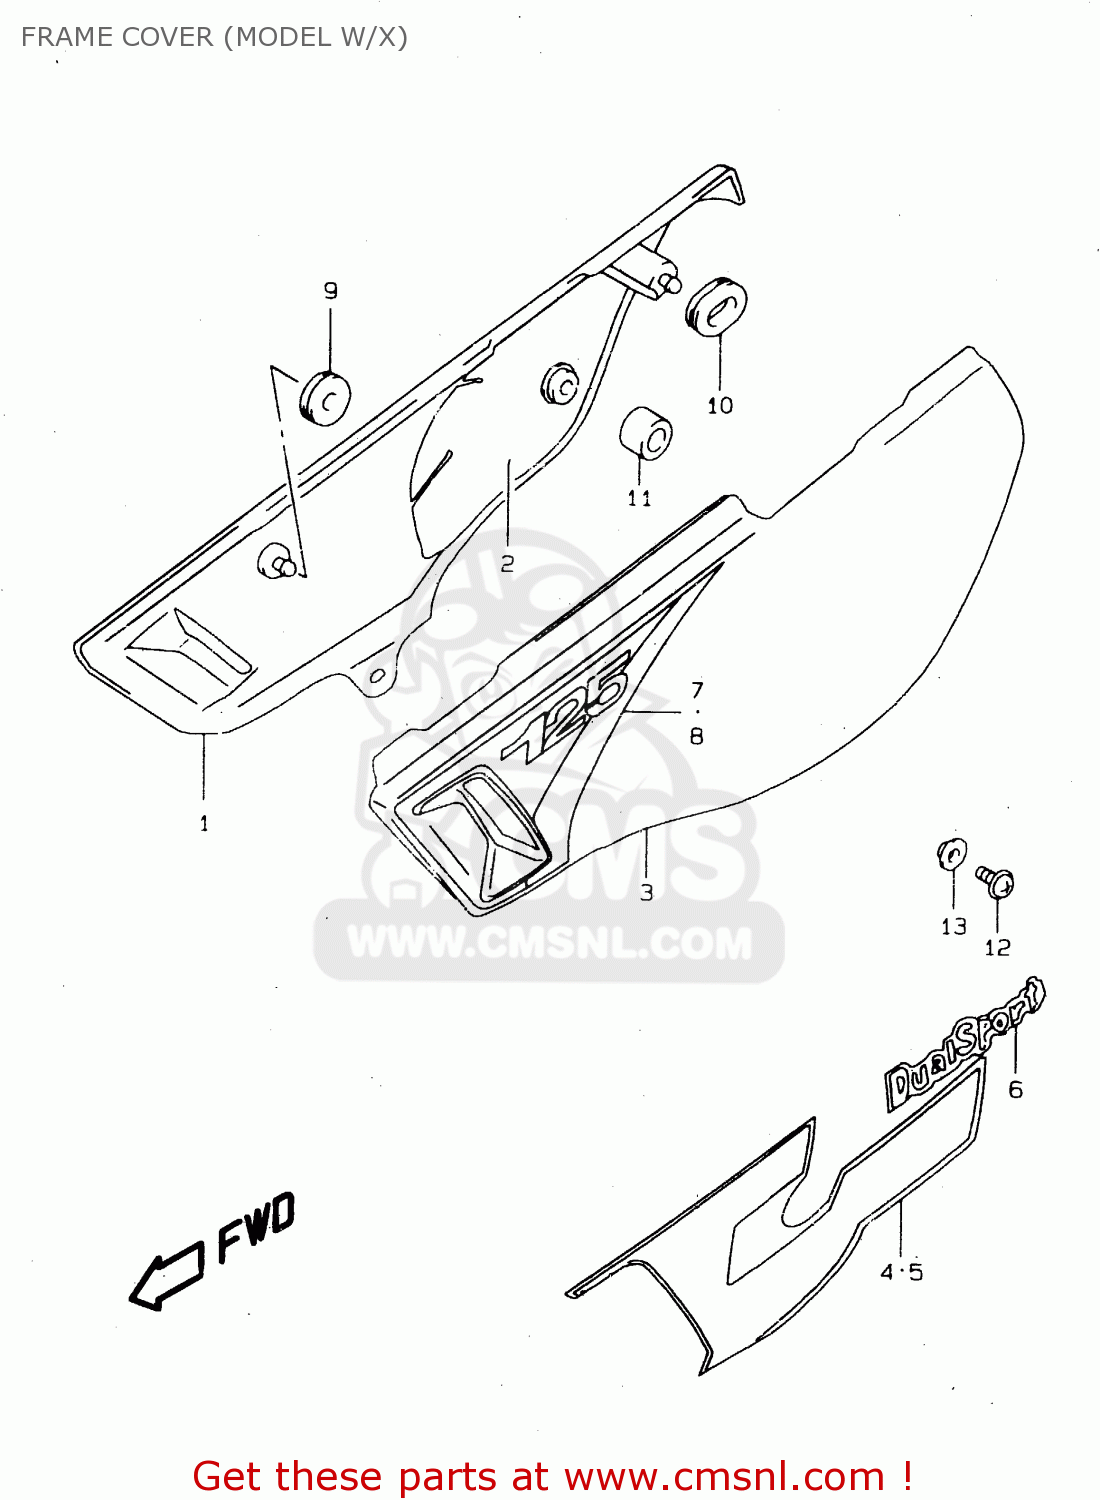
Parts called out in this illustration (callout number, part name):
1	COVER,FRAME,R(WHITE)
2	SHIELD,FRAME COVER,R
3	COVER FRAME,L(
4	TAPE,FRAME COVER,R
5	TAPE,FRAME COVER,L
6	EMBLEM,FRAME COVER
7	TAPE,FRAME COVER,R
8	TAPE, LH
9	CUSHION
10	CUSHION
11	CUSHION
12	SCREW(6X16)
13	WASHER
